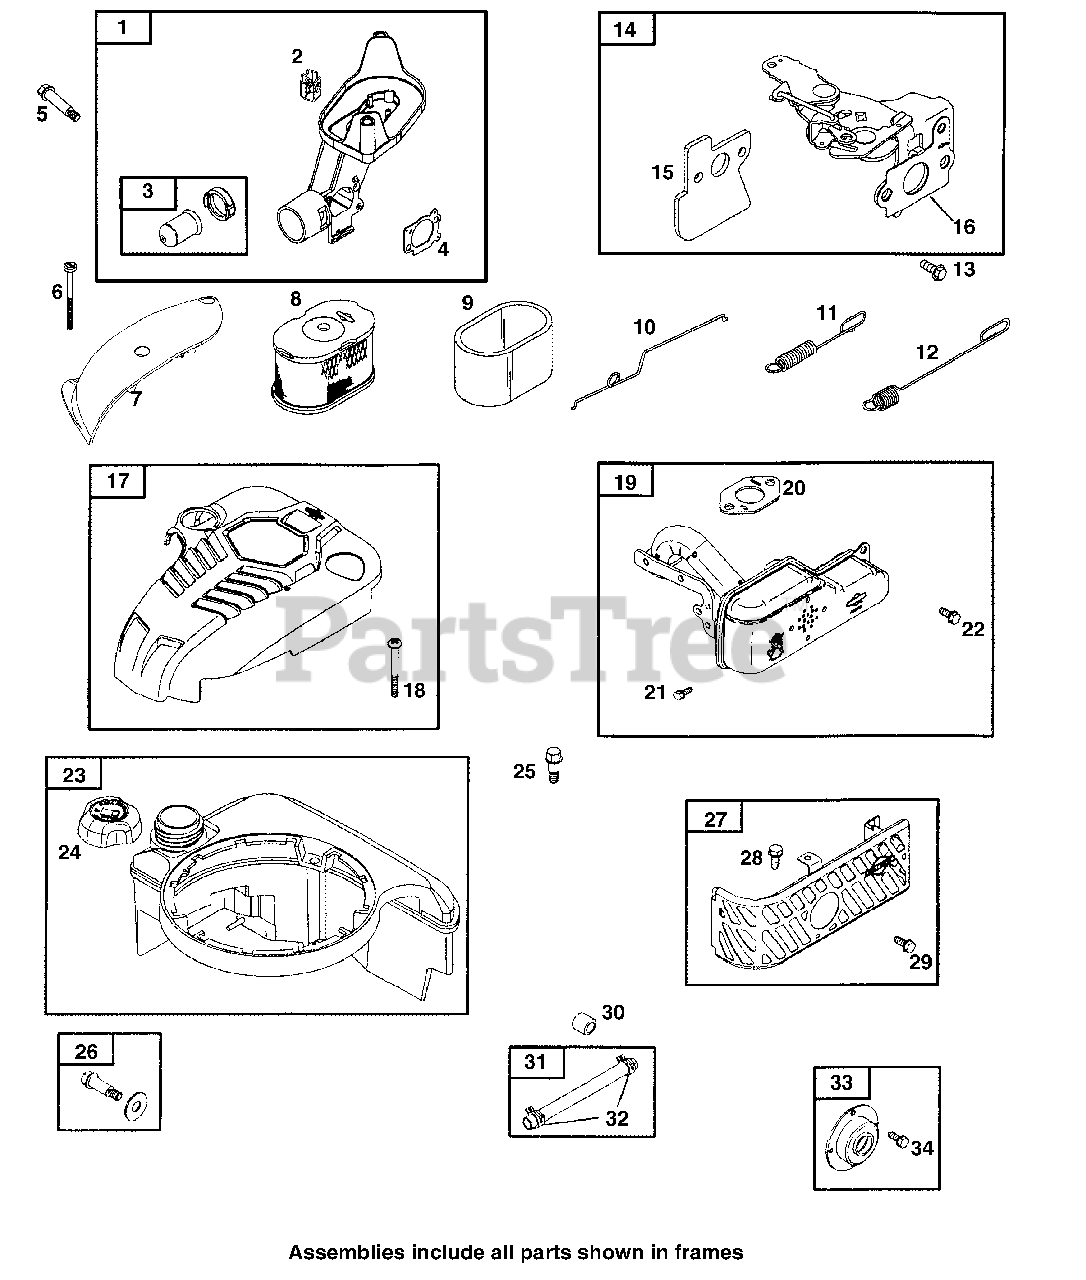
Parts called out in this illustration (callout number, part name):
1	A/C Primer Base
2	Casing Clamp Bracket
3	Carburetor Primer
4	Air Cleaner Gasket
5	Hex Screw
6	Shoulder Screw
7	Air Cleaner Cover
8	A/C Cartridge Filter
9	Pre-Cleaner Filter
10	Mechanical Governor Link
11	Governor Idle Spring
12	Governor Spring
14	Control Bracket
15	Carburetor Spacer
16	Intake Gasket
17	Blower Housing Cover
18	Phillips Screw
19	Exhaust Muffler
20	Exhaust Gasket
21	Hex Screw
22	Hex Screw
23	Fuel Tank
24	Fuel Tank Cap
25	Shoulder Screw
26	Screw/Washer Kit
27	Muffler Guard
28	Hex Screw
29	Hex Screw
30	Fuel Tank Spacer
31	Fuel Line
32	Hose Clamp
33	Muffler Deflector
34	Hex Screw
